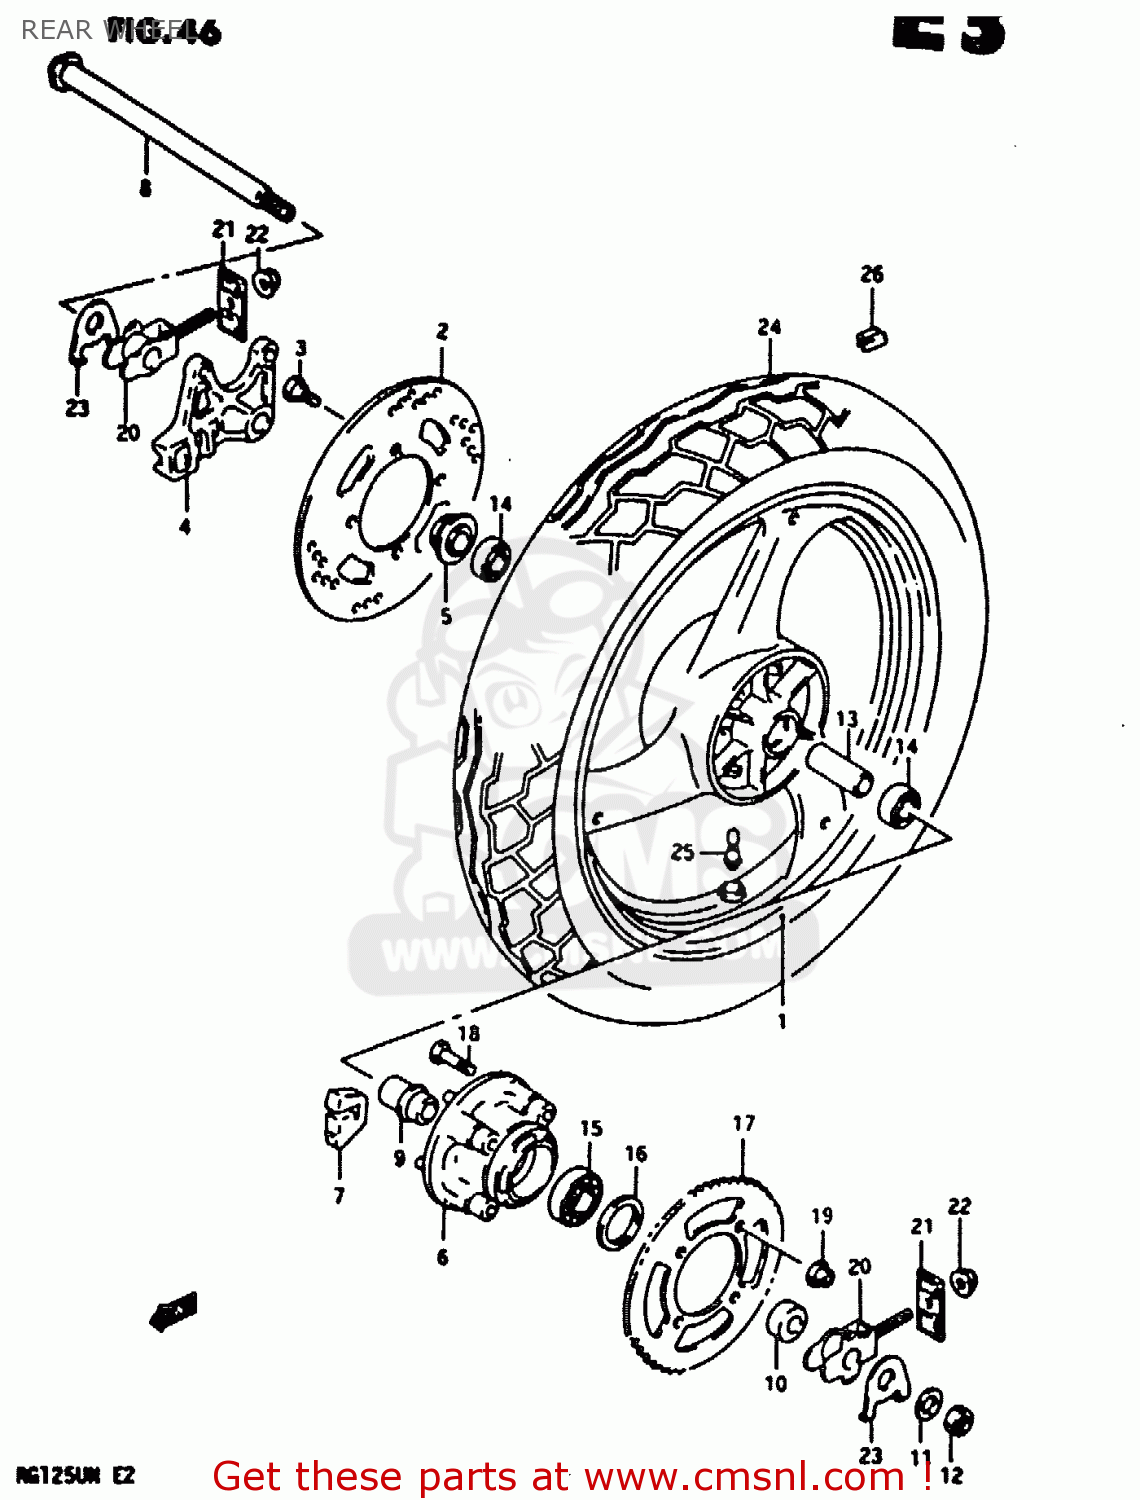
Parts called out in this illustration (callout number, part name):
1	WHEEL, REAR (17*MT2.75) (RED)
2	DISC,RR BRAKE
3	BOLT,BRAKE DISC
4	BRACKET, REAR CALIPER
5	SPACER,RR AXLE,L
6	DRUM,RR SPROCKET MOUNTING
7	ABSORBER,RR HUB SHOCK
8	AXLE, REAR
9	RETAINER,RR SPROCKET DRUM
10	SPACER(17X34X16.5)
11	WASHER(17X30X3)
12	NUT 16MM
13	SPACER(17.5X25X81)
14	BEARING
15	BEARING(25X52X15)
16	SEAL,OIL(34X52X6)
17	SPROCKET, REAR (NT:47)
18	BOLT(10X47)
19	NUT
20	ADJUSTER, CHAIN
21	PLATE,CHAIN ADJUSTER GUIDE
22	NUT
23	WASHER,CHAIN ADJUSTER
24	TIRE, REAR (120/80-17 615) (CUNLOP)
25	VALVE ASSY,WHEEL RIM(TR412)
26	BALANCER,WHEEL
